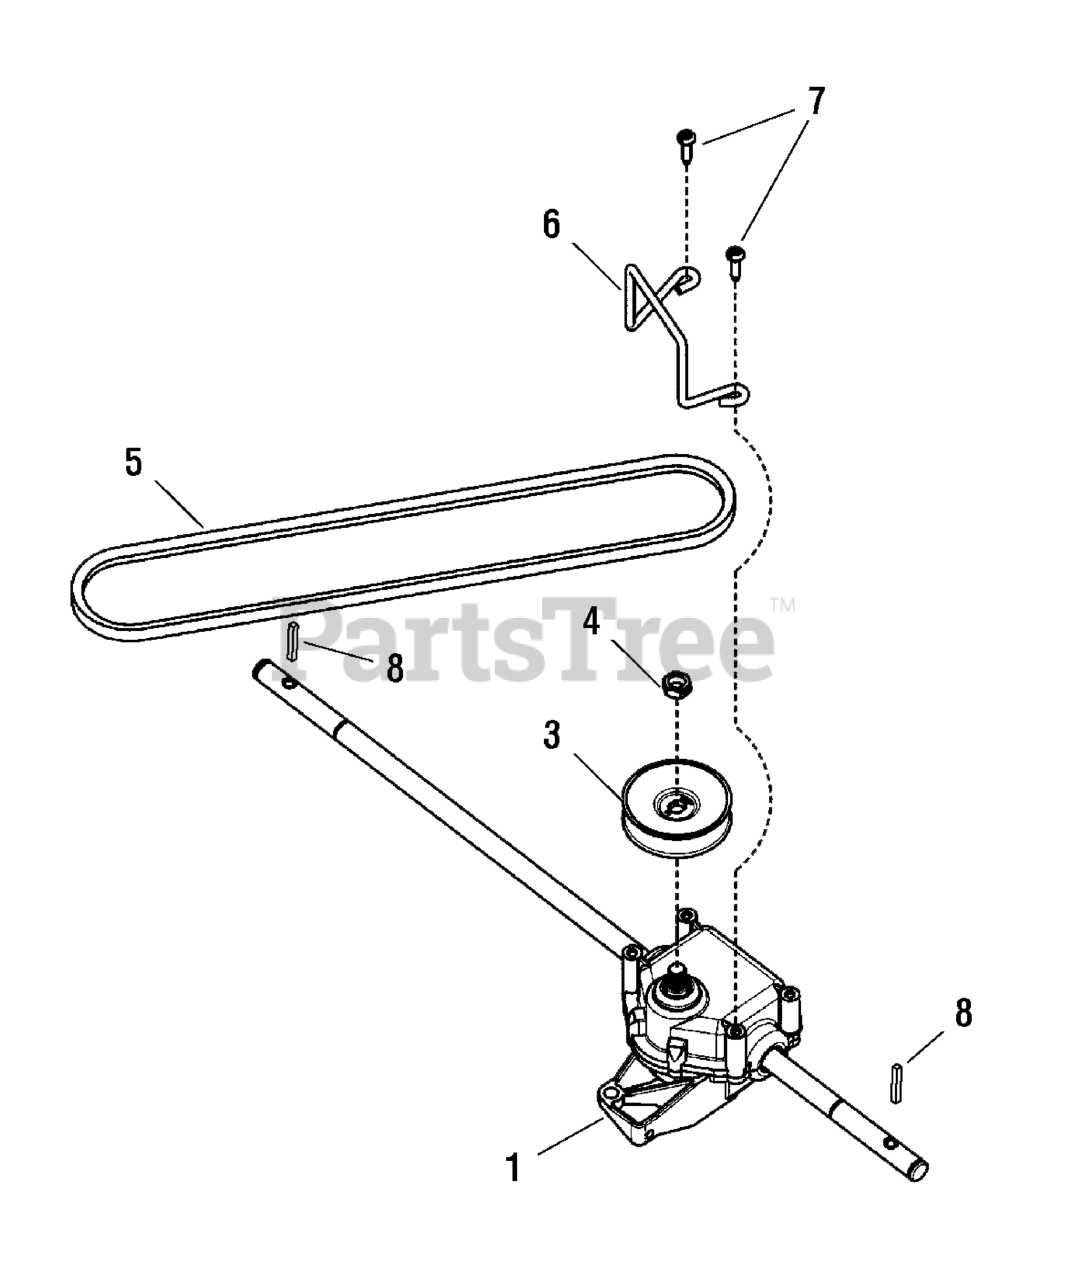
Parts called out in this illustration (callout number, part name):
1	TRANSMISSION
3	PULLEY
4	NUT, Hex Center Lock, 3/8-16
5	BELT, Traction Drive
6	BELT GUIDE, Transmission
7	SCREW, Pan Head, Self Tap, #10-16 x 3/4
8	PIN, Axle
